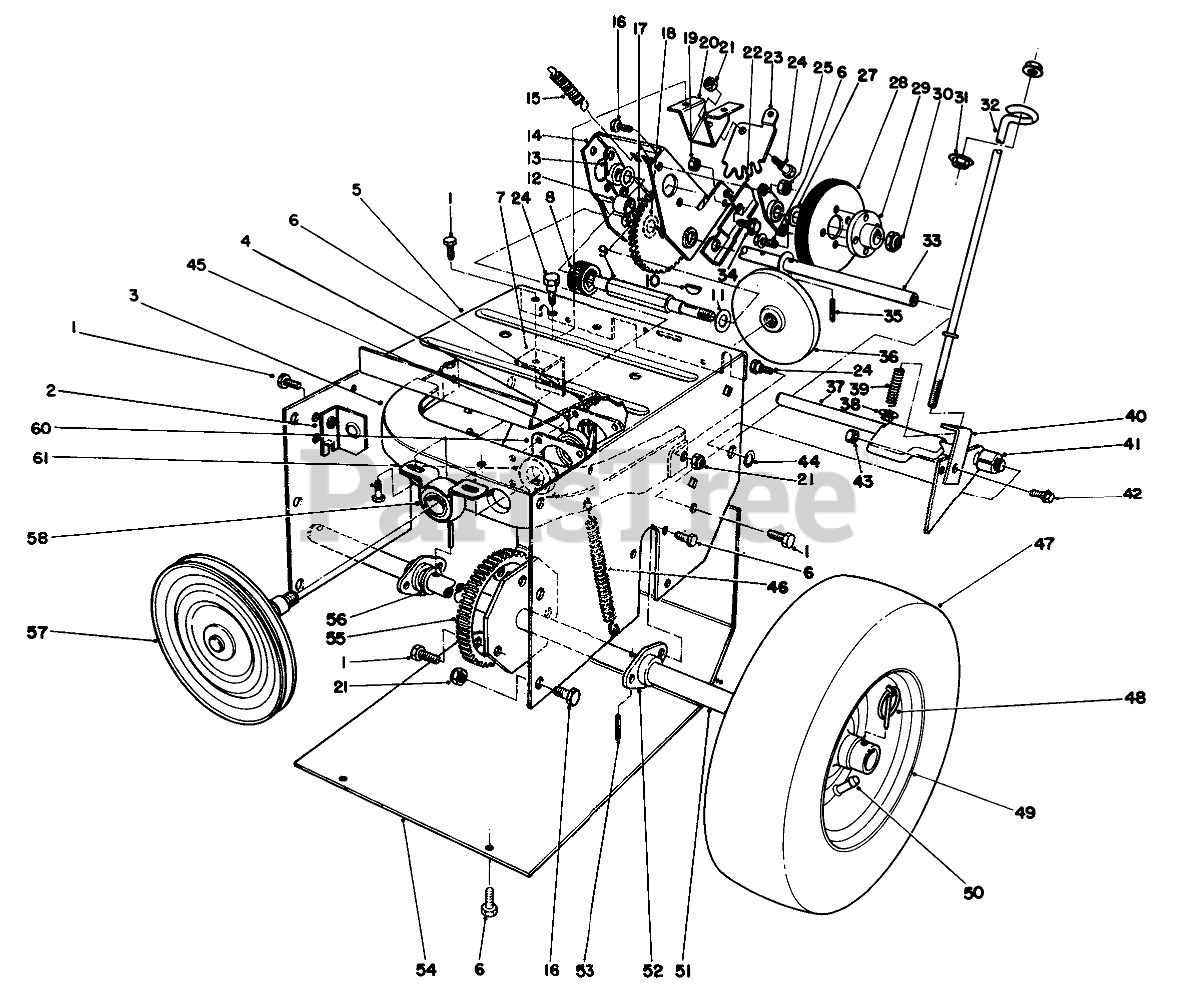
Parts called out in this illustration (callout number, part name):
1	SCREW-HWHTF
2	BRACKET-MOUNT, FRONT
3	"OBS" FRICTION PLT FRAME
4	CUP-BEARING
5	Frame-Traction
6	SCREW-HWH
7	BRACKET-MOUNT, REAR
8	PINION
9	SHAFT-WHEEL, FRICTION
10	KEY-WOODRUFF
11	WASHER-FLAT
12	5/8ID X 1LG BUSHING
13	BEARING-WHEEL, FRICTION
14	BRACKET-SLIDING
15	SPRING-TRACTION
16	SCREW-HH
17	Intermediate Gear & Bushing (Incl. Ref. #12)
18	WASHER-SPECIAL
19	NUT-LOCK, NI
20	MOUNT-LEVER
21	NUT-LOCK, NI
22	CAM-RECEIVER
23	GEAR-QUADRANT
24	BOLT-SHOULDER
25	NUT-LOCK, NI
27	WASHER-THRUST
28	WHEEL-FRICTION
29	HUB-WHEEL, FRICTION
30	NUT-LOCK, NI
31	NUT-HF
32	ROD-TRACTION, LOWER
33	SHAFT-PIVOT
34	SCREW-HH
35	PIN-SPRING
36	PLATE-FRICTION
37	Traction Engagement Asm.
38	NUT-HHF
39	SPRING
40	BRACKET-TRACTION
41	SPACER
42	SCREW
43	NUT-LOCK, NI
44	RING-RETAINING
45	BEARING-BALL
46	SPRING-PLATE, FRICTION
48	PIN-LYNCH
49	WHEEL
51	AXLE SHAFT WA
52	BEARING-AXLE
53	PIN-SPRING
54	Bottom Cover
55	GEAR-AXLE
56	WASHER-THRUST
57	Pulley & Shaft
58	BUSHING ASM
59	SCREW-HWHTF
60	BEARING GASKET
61	Gasket-Bearing
